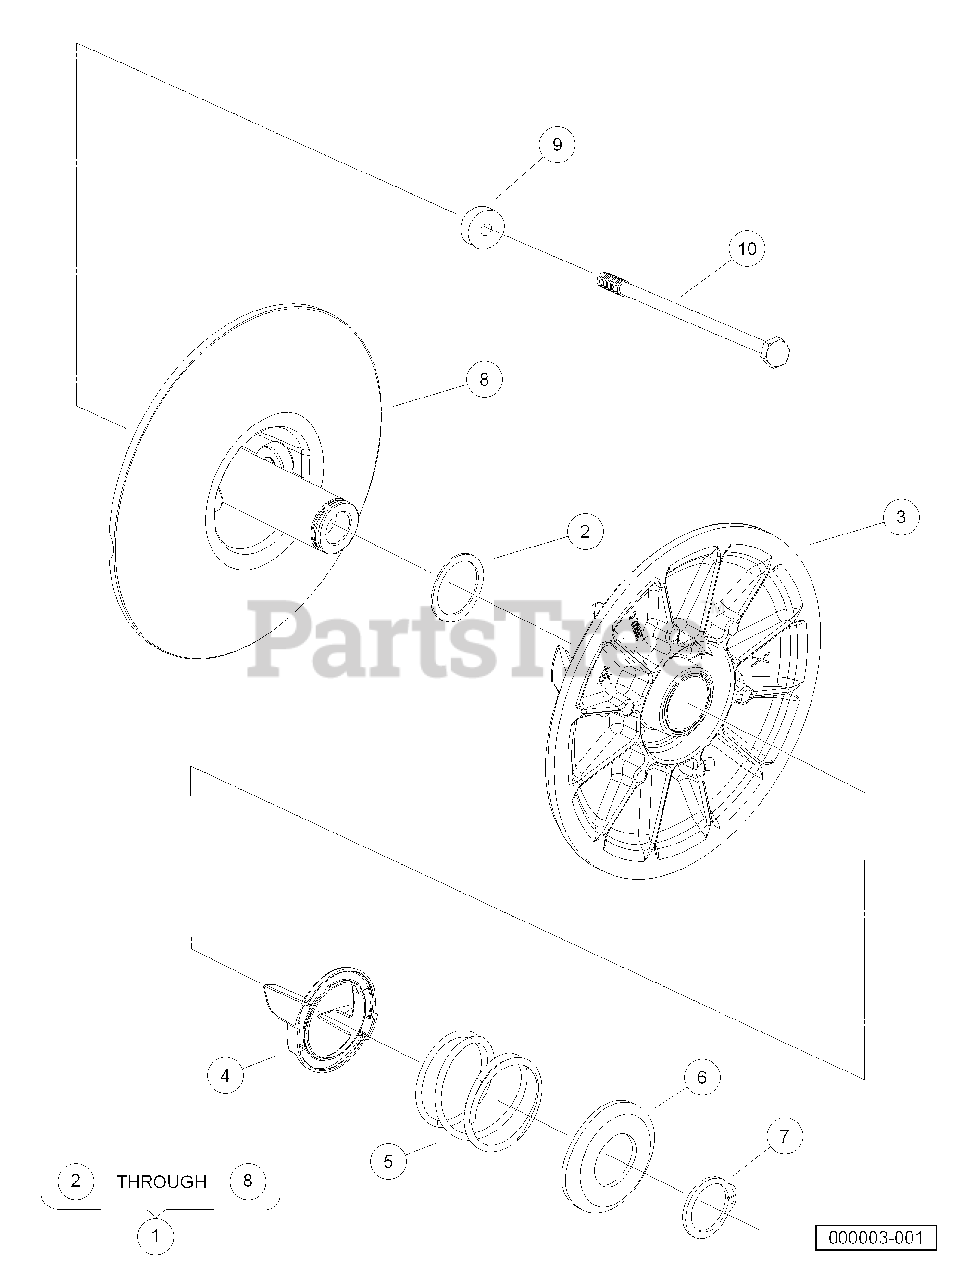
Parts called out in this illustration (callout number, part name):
1	CVT, Secondary
2	3asher, Thrust, 1.53 X 1.92
3	Sheave, Driven Clutch
4	Retainer, Spring, Inner
5	Spring, Compression, Secondary
6	Retainer, Spring, Outer
7	Ring, Retaining, External
8	Driven Clutch Base Sheave
9	Washer, Stepped
10	Bolt, M10 X 1.5 X 100 Loctite
